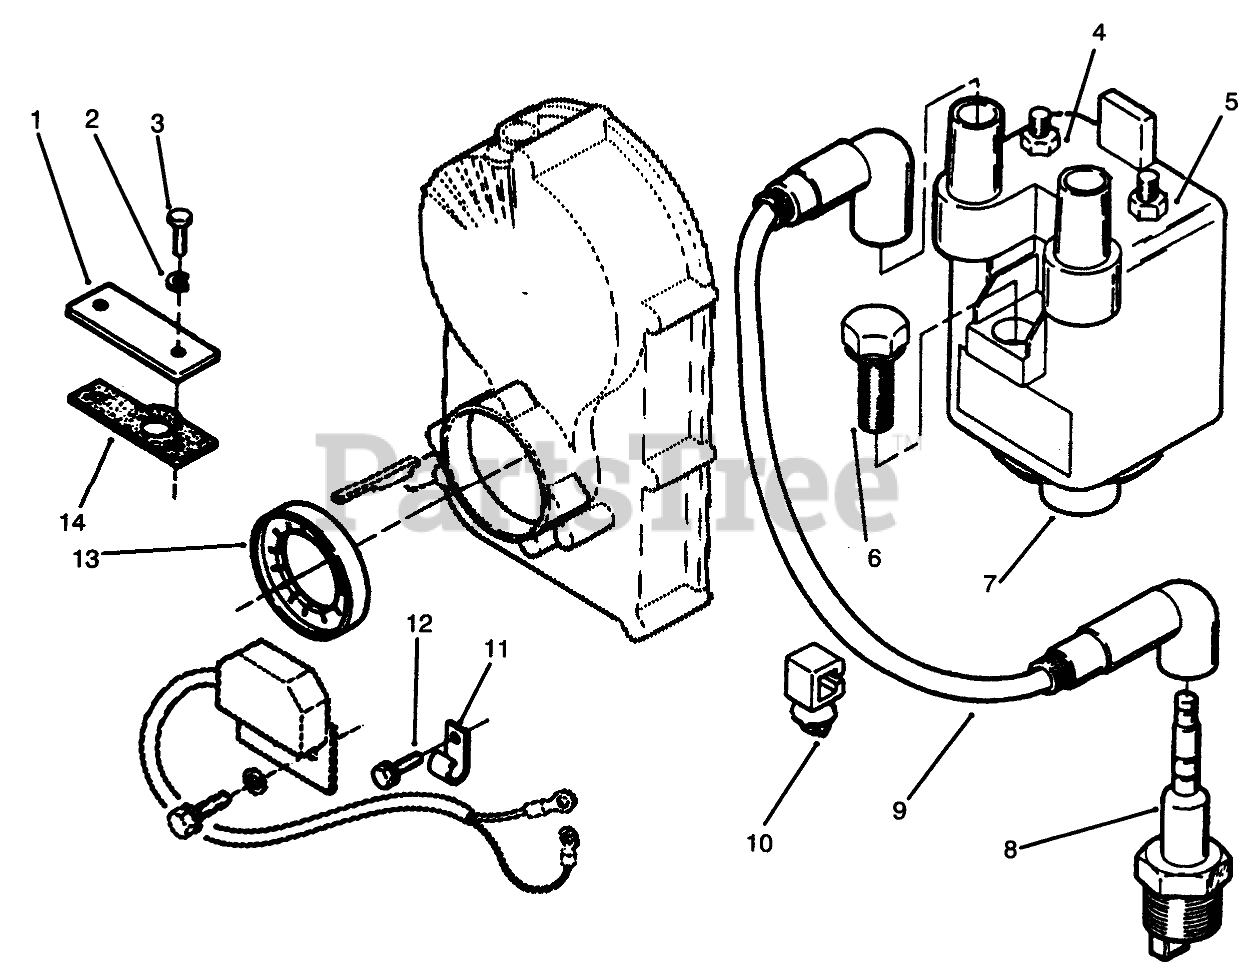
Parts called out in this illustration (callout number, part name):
1	PLATE-COVER
2	WASHER-FLAT
3	SCREW - CAP HEX HEAD
4	NUT-HEX FLANGE
5	NUT-HEX FLANGE
6	HEX-HEAD CAP SCREW
7	Coil-Battery Ignition (Incl. Ref. #4-5)
8	SPARK PLUG
9	Wire-Plug
10	WIRE ROUTING CLIP
11	CLIP-WIRE
12	SCREW-HH
13	ROTOR-IGNITION
14	Gasket-Plate
